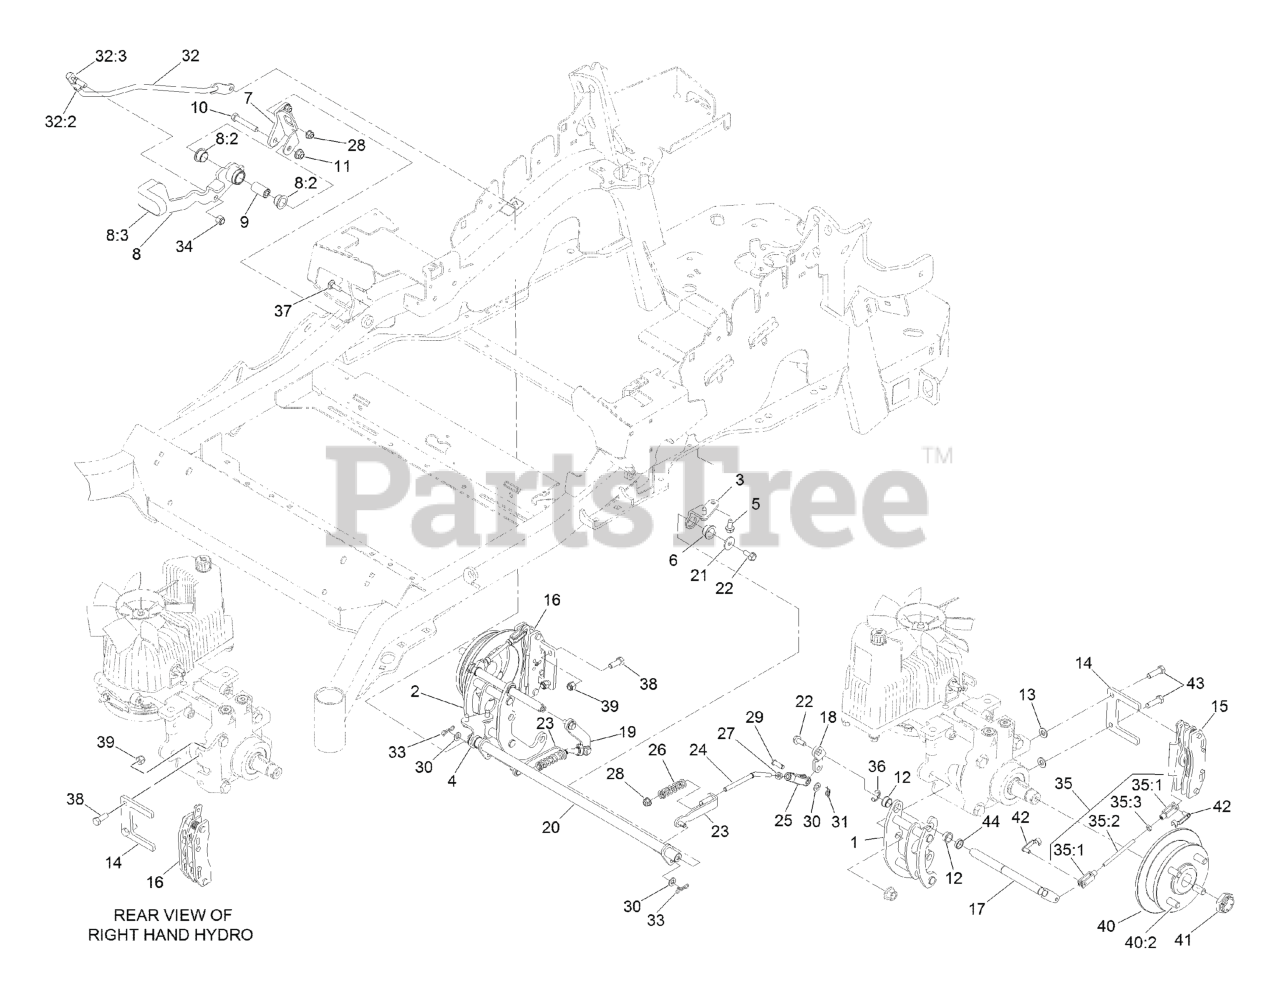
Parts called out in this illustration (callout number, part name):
1	MOUNT-BELLCRANK, LH
2	MOUNT-BELLCRANK, RH
3	MOUNT-PIVOT, LH
4	MOUNT-PIVOT, RH
5	Screw-HWH 5/16-18 X 3/4 Tf
6	BUSHING-FLANGE
7	BRACKET-MOUNT
8	BRAKE LEVER ASM W/ GRIP
8:2	BUSHING-FLANGE
8:3	GRIP-LEVER
9	HANDLE-PIVOT, BRAKE
10	SCREW-HH
11	NUT-HF, NI
12	BUSHING
13	WASHER-FLAT
14	PLATE-MOUNT, BRAKE
15	CALIPER-BRAKE
16	CALIPER-BRAKE, RH
17	BELLCRANK
18	ARM-INNER, LH
19	ARM-INNER, RH
20	SHAFT-CROSS
21	WASHER-FLAT
22	SCREW-HHF
23	BRACKET-L
24	LINKAGE-MID
25	YOKE-OFFSET
26	SPRING-COMPRESSION
27	NUT-JAM
28	NUT-HF, NI
29	PIN-CLEVIS
30	WASHER-PLAIN
31	PIN-COTTER, LOCKING
32	FRONT LINKAGE ASM
32:2	END-TIE ROD, RH
32:3	NUT-HJ
33	PIN-COTTER, LOCKING
34	NUT-LOCK
35	REAR LINKAGE ASM
35:3	NUT-JAM
37	BOLT-CARR
38	SCREW-HH
39	NUT-LOCK, NI
40	WHEEL HUB ASM
40:2	STUD-WHEEL
41	LOCKNUT
42	PIN-CLEVIS, SPRING
43	SCREW-LOCK, PATCH
